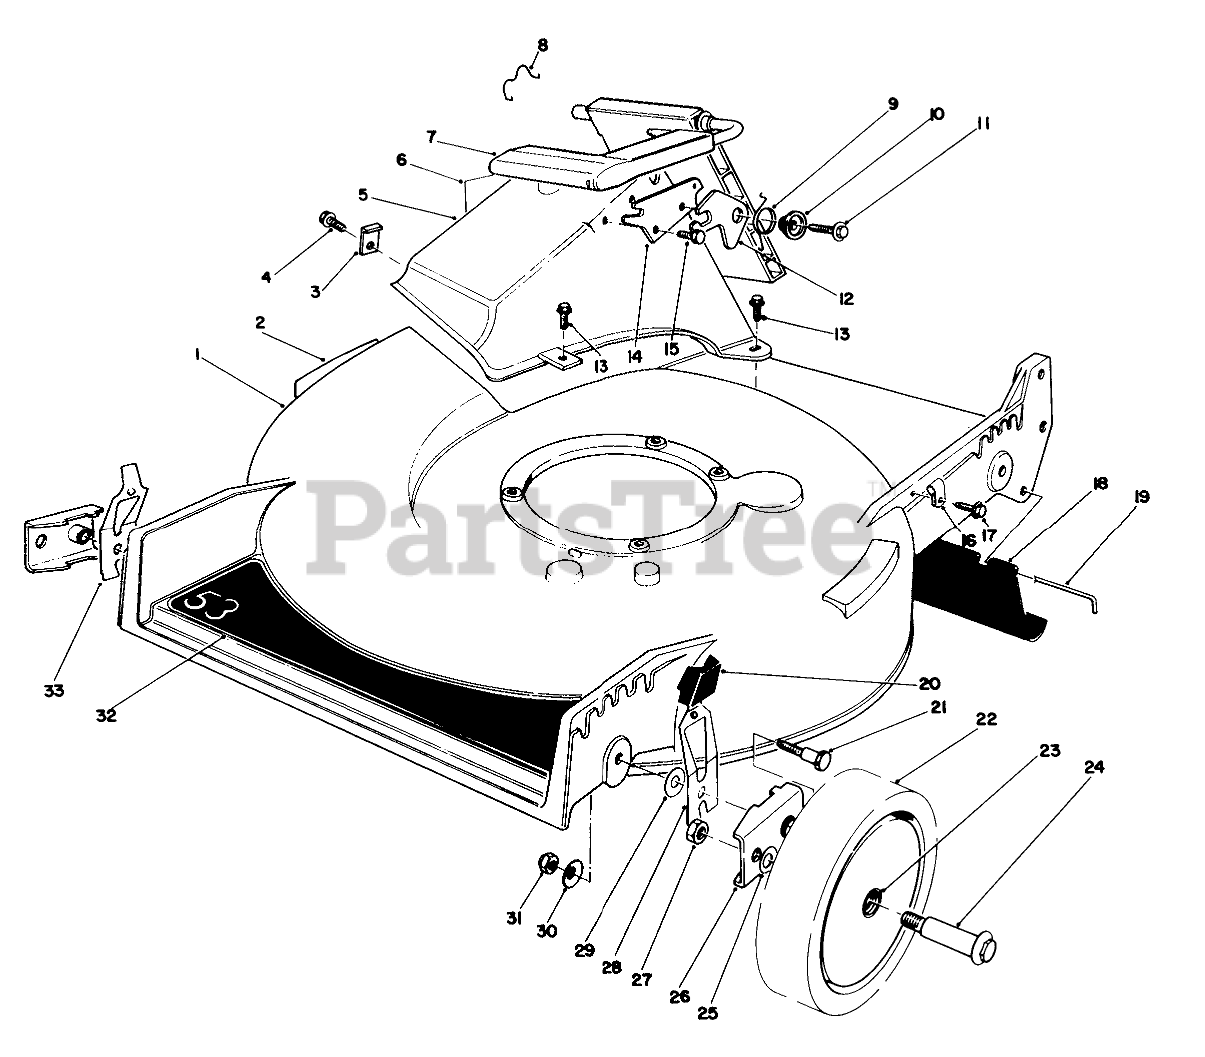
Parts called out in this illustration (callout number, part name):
1	Housing (Incl. Ref. #2)
2	Decal Danger
3	TUNNEL CLIP
4	SCREW
5	Tunnel-Discharge (Incl. Ref. #6)
6	DECAL - DANGER
7	Discharge Door Assembly
8	DOOR RET SPRING
9	TORSION SPRING
10	DOOR SPACER
11	SCREW-HWH
12	SAFETY LATCH
13	SCREW-HWH
14	DOOR LATCH PLATE
15	SCREW-PLASTITE
16	CLAMP-CABLE
17	SCREW
18	SHIELD-TRAILING
19	ROD-SHIELD
20	KNOB-ARM
21	PIVOT SCREW
22	Wheel & Tire Assembly (Inc. Ref. #23)
23	BUSHING
24	BOLT-WHEEL
25	WASHER
26	HP PIVOT ARM ASM
27	Nut
28	L. HP SPRING ARM ASM
29	WASHER-PIVOT
30	WASHER-BELLEVILLE
31	NUT-LOCK, NI
32	Decal-53
33	R HP SPRING ARM ASM
